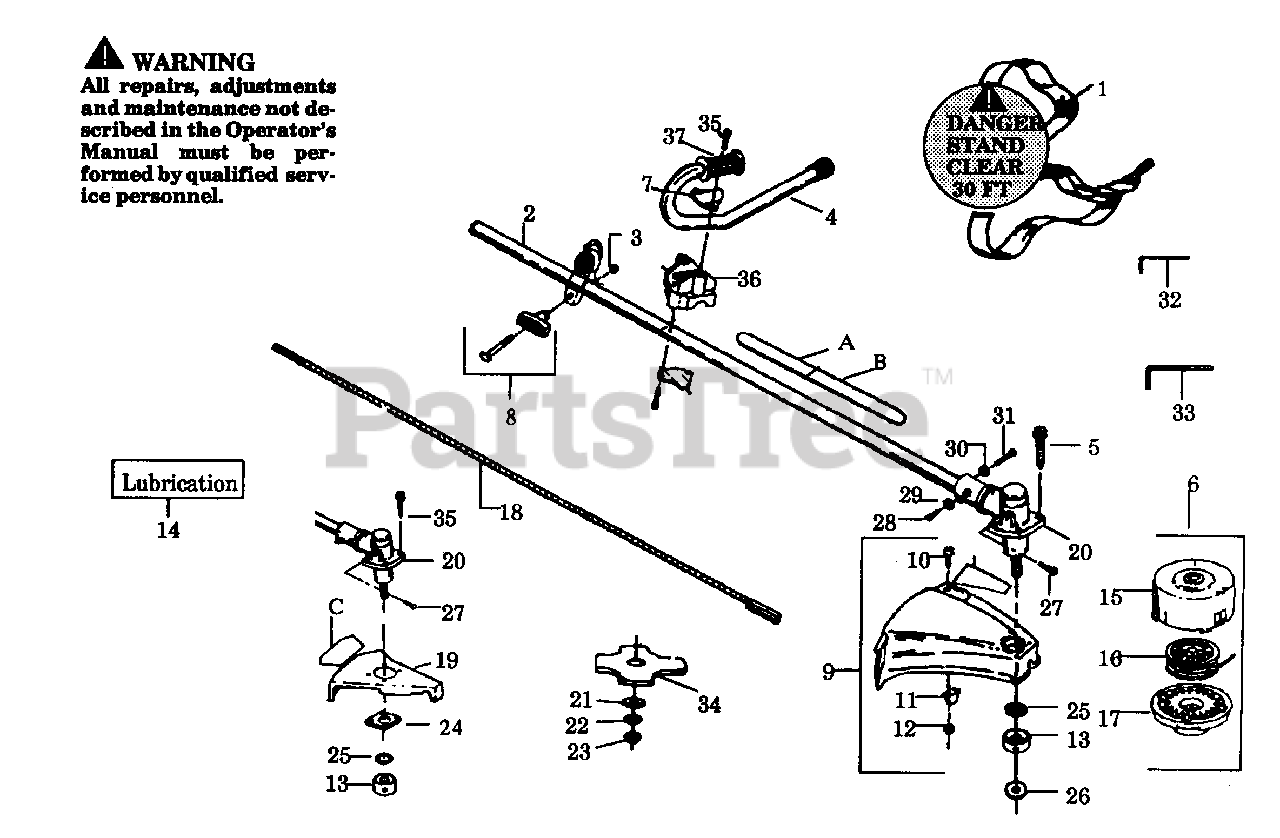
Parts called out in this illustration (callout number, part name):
1	Shoulder Strap
2	Drive Shaft Housing
4	Handlebar
5	Screw
6	Cutting Head Ass'y. (Inc.15,16,17)
7	Handlebar Bracket
8	"T" Handle" Ass'y.
9	Shield Kit Ass'y. (Inc.10,11,12)
11	Line Limiter
12	Locknut
13	Dust Cup
14	Shaft Lubrication
15	Hub Ass'y
16	Spool w/Line
18	Drive Shaft
19	Shield
20	Gear Box Ass'y.
22	Washer
24	Shield Retention Plate
26	Grass Washer
29	Lockwasher
30	Lockwasher
32	Hex Wrench (5/32)
33	Hex Wrench (3/16)
34	Weed Blade
36	Handlebar Clamp
37	Handlebar Grip
A	Safety Label (Upper)
B	Safety Label (Lower)
C	Blade Direction Decal (Not a serviceable part)
